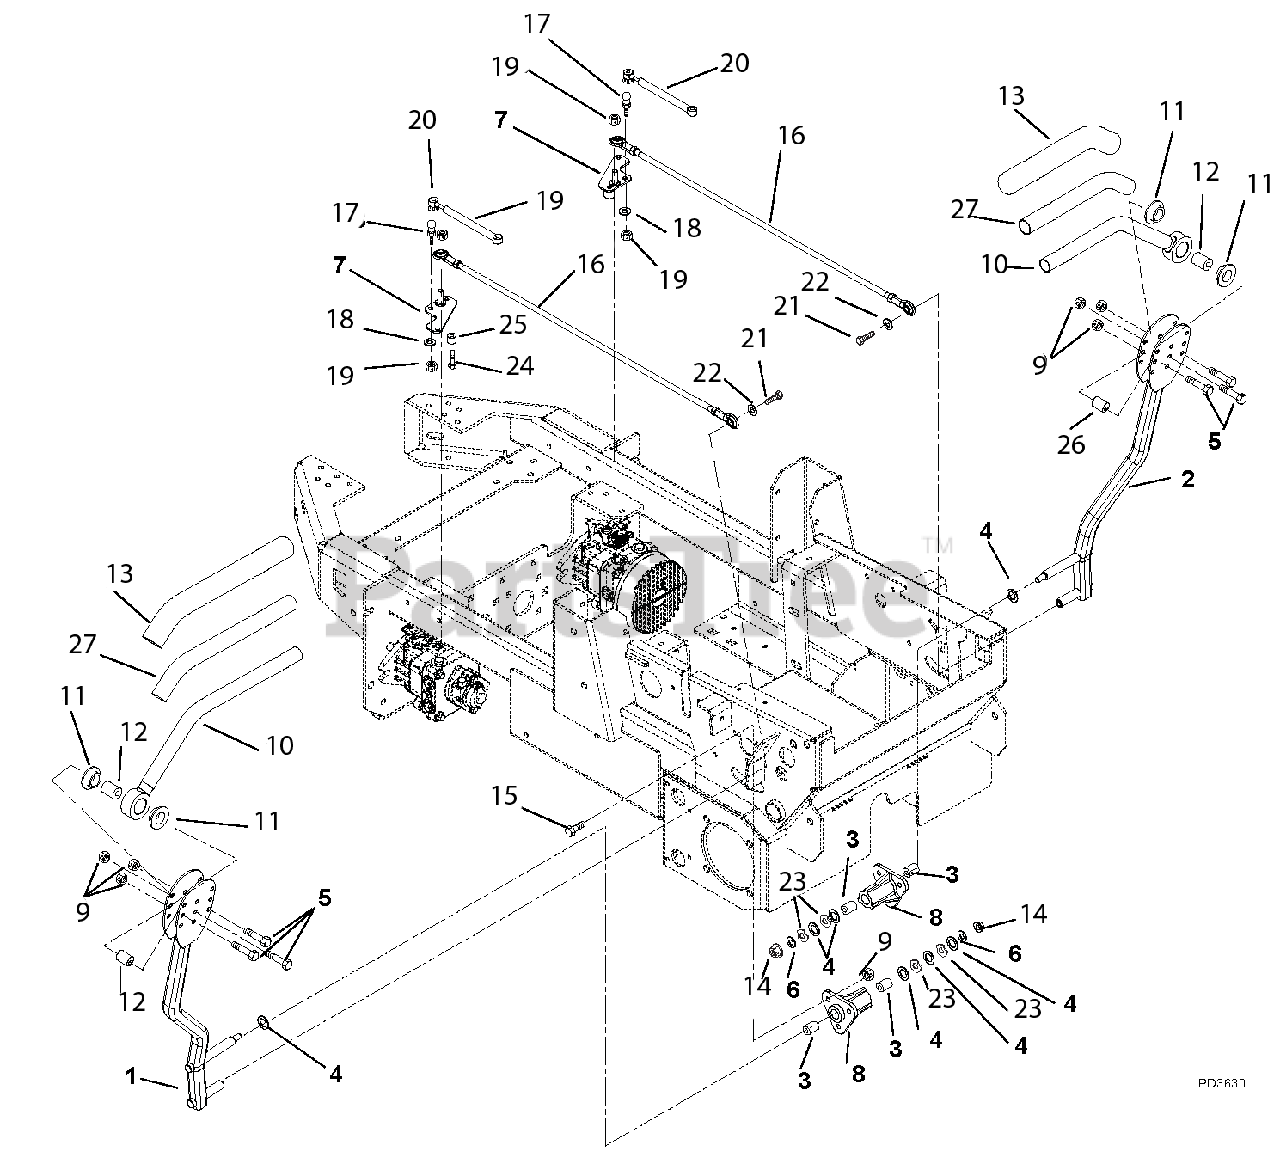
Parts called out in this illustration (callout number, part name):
1	WMT, BENT STEERING ARM-RH
2	WMT, BENT STEERING ARM-LH
3	BSHG .625X.750X.500
4	WSHR-FL-STL .630X1.005X.062 YZ
5	@BLT-HEX .31-18X1.75 GR5 YWZC
6	@WSHR-FL-STL.438X1.00X.083 YWZ
7	WMT, RTN/DAMPER/STEERING (OF)
8	BUSHING, FLANGE
9	@NUT-LK-NYL-FLG .31-18 YWZC
10	HANDLE WLDMT LH
11	BSHG-FLG .762X1.48X.44 NYL
12	SPACER .328 X .76 X 1.01
13	GRIP, HANDLEBAR 1.00X1.38X11.3
14	@NUT-LK-NYL-FLG .38-16 YWZC
15	@BLT-RDHDSQNK .31-18X1.00 G5YZ
16	ASSY, STEERING ROD .38 ROD
17	STUD- BALL
18	@WSHR-LK .31X.078 REG YWZC
19	@NUT-LK-NYL-FLG .31-18 YWZC
20	DAMPER, CONTROL
21	BLT-HEX .38-16X1.0 GR8 YZ EP30
22	@WSHR-FL-STL.406X.812X.065 YWZ
23	WAVE WASHER .640X.875X.125FH
24	@BLT-HEX .31-18X1.25 GR5 YWZC
25	SPACER .318X.430X.375
26	BSHG, ECCENTRIC .328X.750X.970
27	TUBE, .88ID X 1.00OD X 10.25
